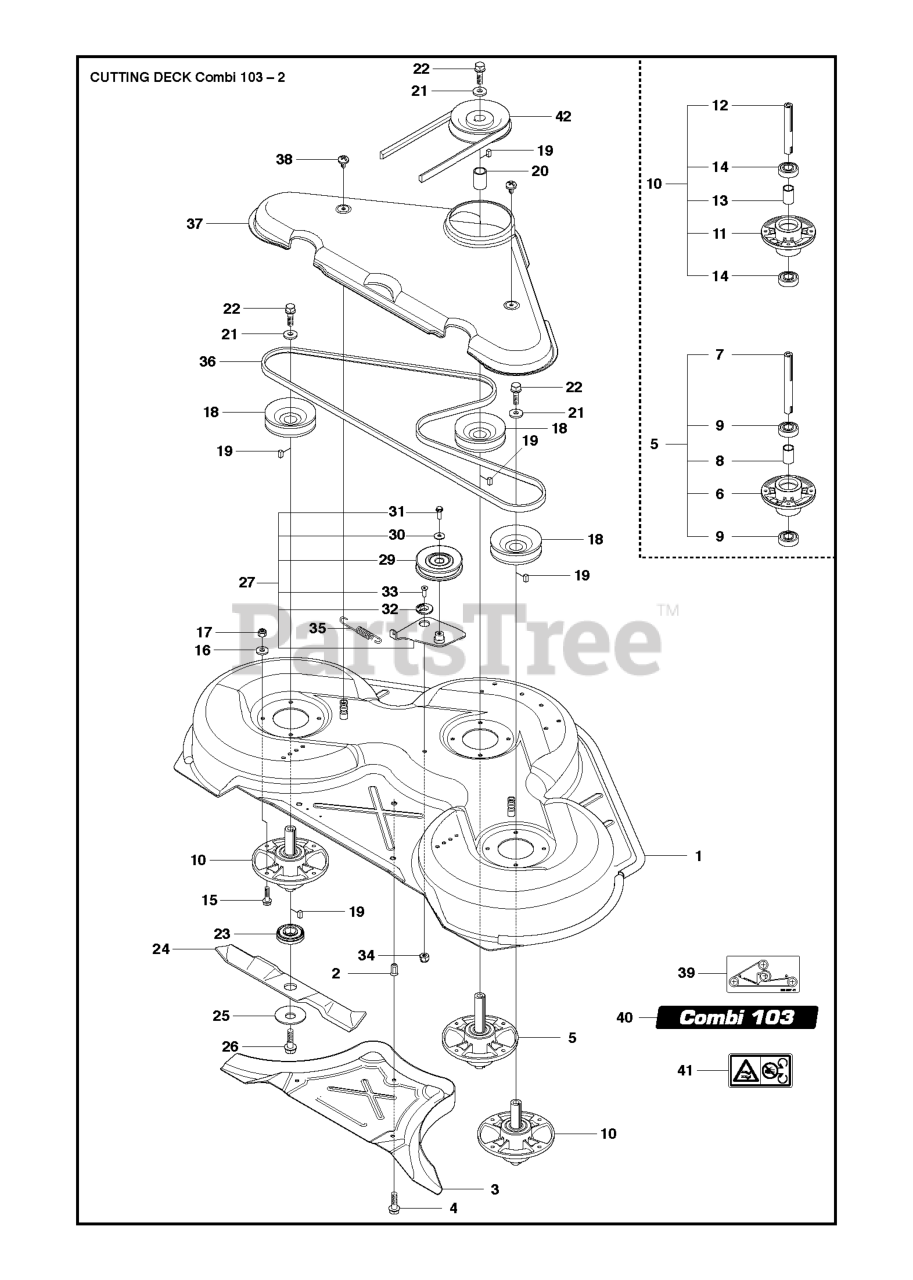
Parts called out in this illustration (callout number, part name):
1	CUTTING DECK RIDER
5	BLADE HOUSING ASSY
6	BEARING HOUSING
8	SPACING SLEEVE
10	BLADE HOUSING ASSY
11	BEARING HOUSING
13	SPACING SLEEVE
16	WASHER BRB 8.4X17
17	LOCKNUT M8
27	BELT TENSIONER ASSY KIT
32	WASHER SHOULDER ASSY
34	LOCKNUT M8
